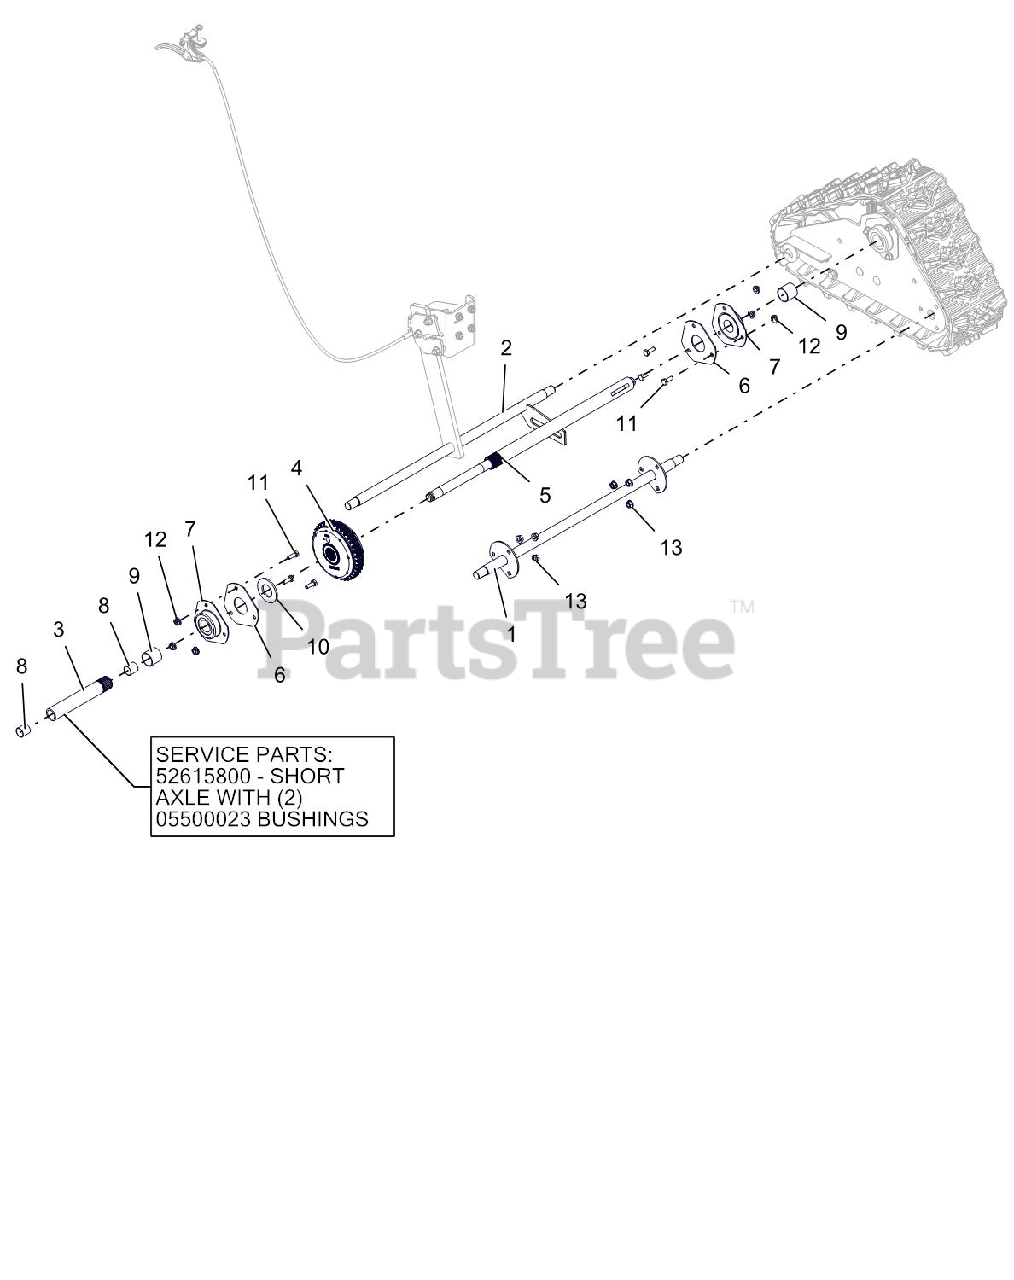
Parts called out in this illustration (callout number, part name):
1	AXLE, FRONT - PRO
2	AXLE, REAR - PRO TRACK
3	BSHG-SLV .706X.764X.75 BRZ
3	AXLE, SHORT-TRACK DIFFERENTIAL
3	AXLE, SHORT-W/BUSHINGS
4	DIFFERENTIAL, AUTOMATIC
5	AXLE, LONG-TRACK DIFFERENTIAL
6	PLATE, BEARING SPACER
7	BRG-FLG 1.003/1.000 3 BOLT
8	BSHG-SLV .706X.764X.75 BRZ
9	BSHG-SLV, 1.012X1.125X1.00
10	WSHR-FL-STL- 1.062X2.0X.134 YZ
11	@BLT-HEX .25-20X.75 GR5 YWZC
12	@NUT-LK-CTR-FLG .25-20 YWZC
13	@NUT-LK-TOP-FLG .25-20 YWZC
